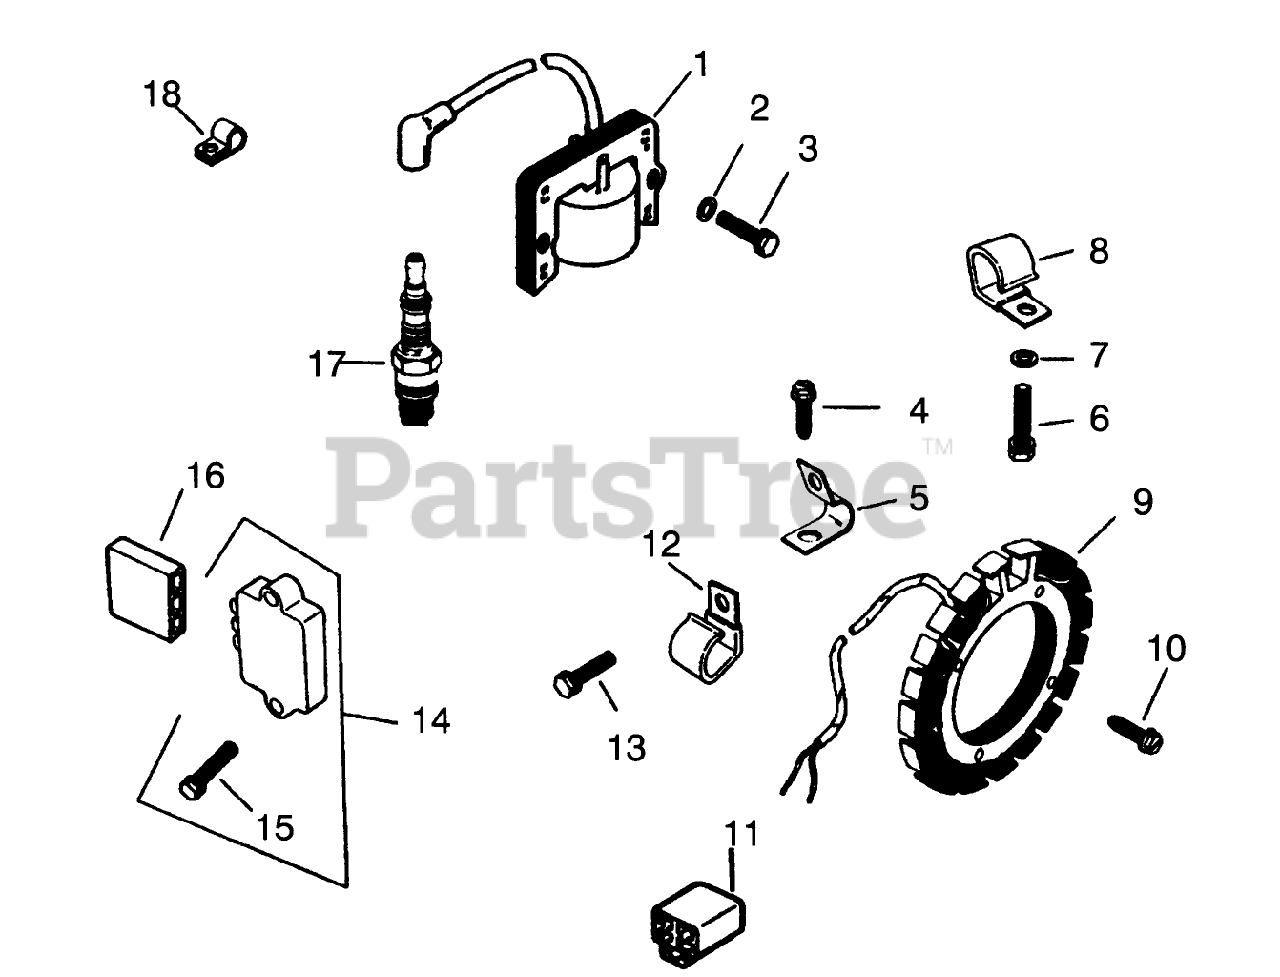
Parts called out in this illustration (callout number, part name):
1	KOHLER 47-584-02
2	KOHLER X-25-79
3	KOHLER X-156-1
4	KOHLER X-67-59
5	KOHLER X-728-1
6	KOHLER X-67-83
7	KOHLER X-25-72
8	Clip
9	KOHLER 237878
10	KOHLER X-67-51
11	KOHLER 48-155-01
12	CLIP
13	SCREW-HH
14	KOHLER 41-403-05
15	KOHLER X-132-4
16	KOHLER 236602
17	KOHLER 235041-5
18	KOHLER 210281
